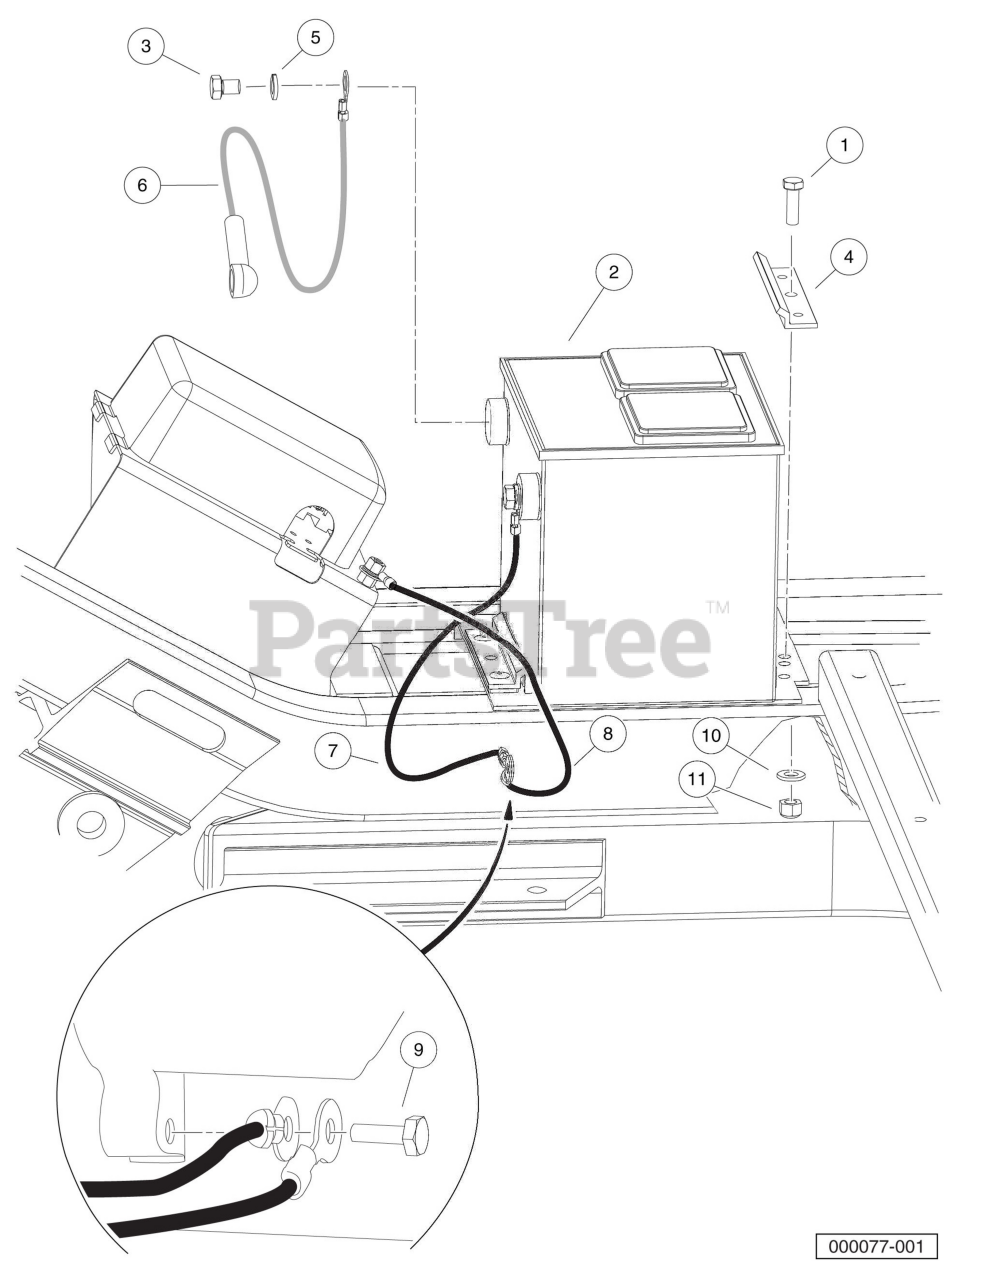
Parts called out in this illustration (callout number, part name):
1	Screw, 5/16-18 X 1.00 Hex Cap
2	Battery, 12-Volt
3	Screw, 3/8-16 X 0.50 Stainless Steel Hex-Head.
4	Clamp, Battery.
5	Lockwasher, 3/8 Stainless Stl
6	Asm, #6 Red Wire.
7	Asm, #6 Blk Wire
8	Asm, #6 Blk Wire
9	Bolt, M6 X 1 X 16 Loctite
10	Washer, 5/16 Type A Flat
11	Locknut, 5/16-18 Nylon Insert
